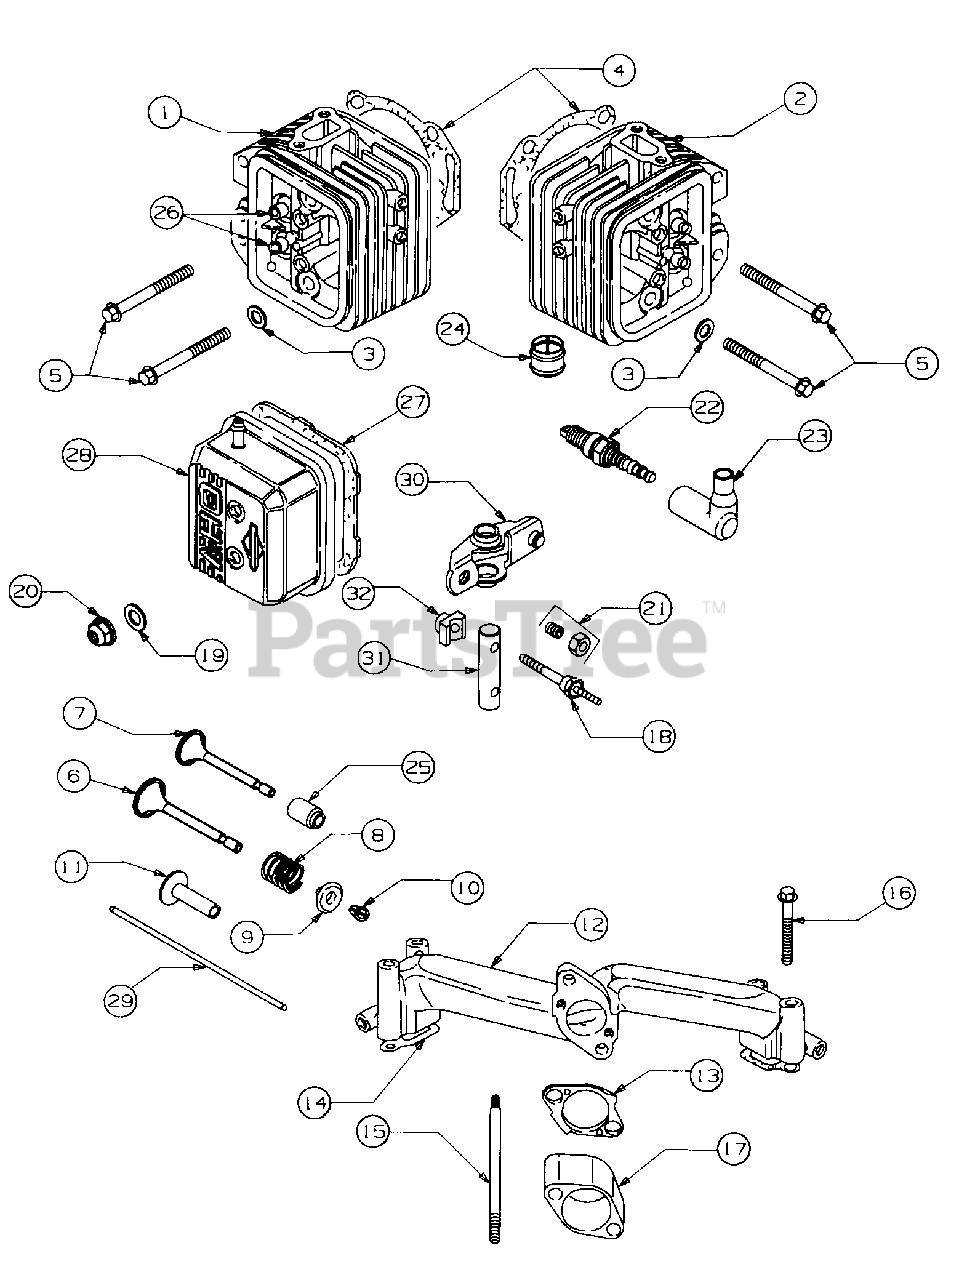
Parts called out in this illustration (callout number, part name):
1	Head, Cylinder #1
2	Head, Cylinder #2
3	Washer, Cylinder Head
4	Gasket, Cylinder Head
5	Screw, Cylinder Head
6	Valve, Exhaust
7	Valve, Intake
8	Spring, Valve
9	Retainer, Valve Spring
10	Retainer, Valve
11	Tappet, Valve
12	Manifold, Intake
13	Gasket, Carburetor Mtg
14	Gasket, Intake Manifold
15	Stud, Carburetor Mtd
16	Screw, Sem
17	Spacer, Carburetor
18	Stud, Rocker Arm
19	Washer, Valve Cover
20	Nut, Nylock
21	Screw, Valve Adjusting
22	Plug, Spark
23	Elbow, Spark Plug
24	Liner, Exhaust Port
25	Seal, Valve Guide
26	Guide, Valve
27	Gasket, Valve Cover
28	Cover Valve
29	Rod Push (Steel)
30	Arm, Rocker
31	Shaft, Rocker Arm
32	Support, Rocker Arm
